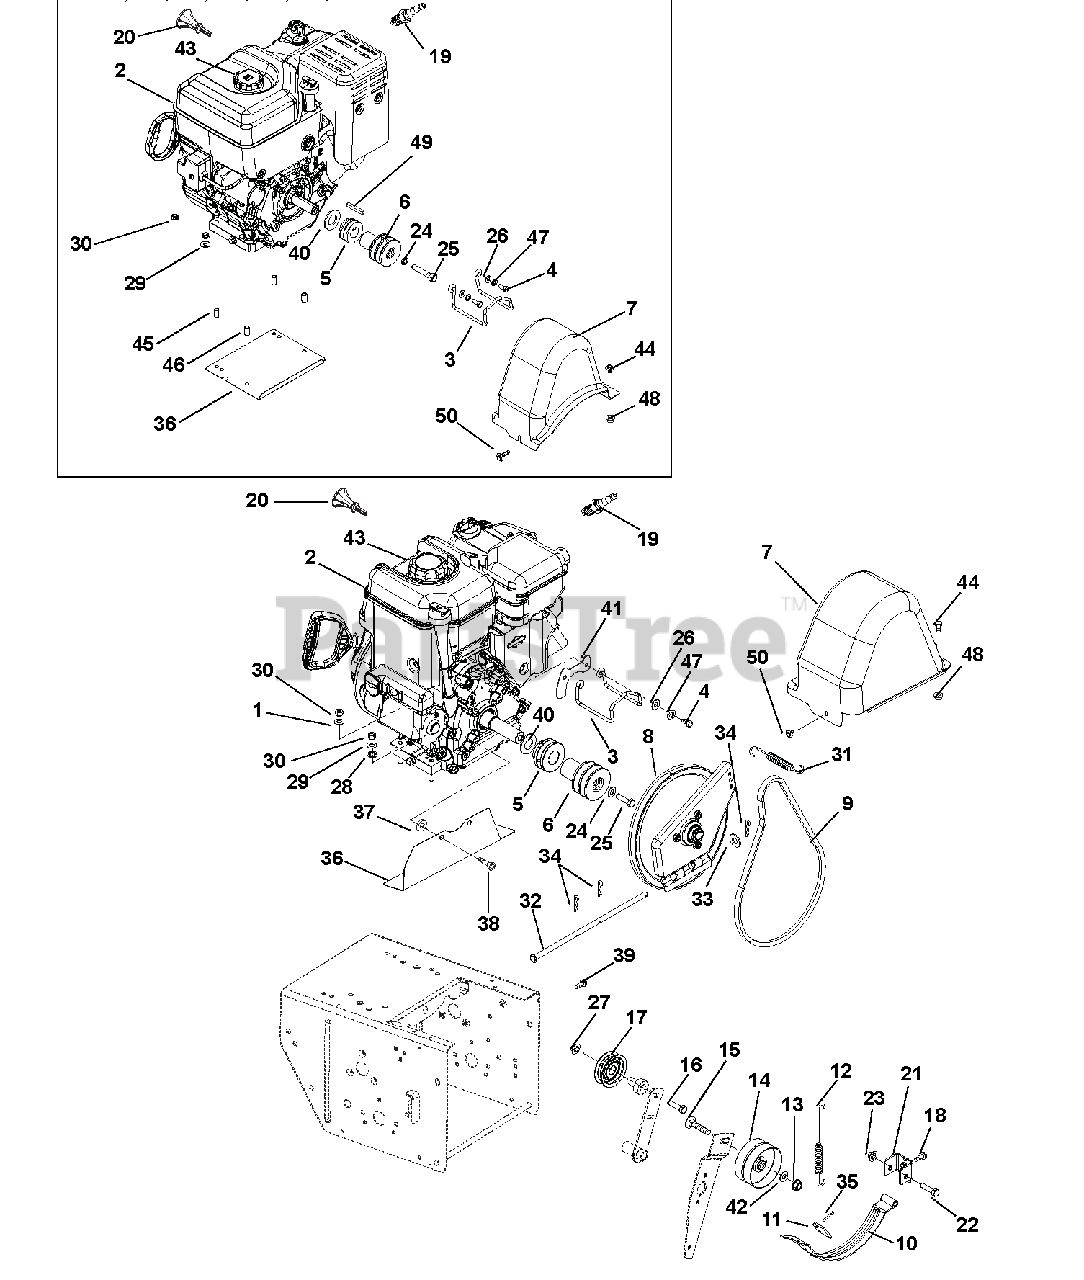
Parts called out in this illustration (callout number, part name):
1	WSHR-LK .312X.097 HVY YWZC
2	ENGINE, BRIGGS PF 1650, 12V
2	ENGINE, BRIGGS PF 2100, 120V
2	ENGINE, BRIGGS PF 2100, 240V
2	ENGINE, BRIGGS PF 2100, 12V
3	FINGER, BELT
4	BLT-HEX .31-24X.75 YWZC GR5
5	SHEAVE, DRIVE
5	SHEAVE, DRIVE 420 BRIGGS
6	SHEAVE, ATTACHMENT 2-GRV
7	COVER, BELT
7	COVER, BELT-LARGE PRO
8	PLATE, SWING ASSEMBLY-DEEP
9	V-BELT, 3L-WRAPPED
10	ARM, BRAKE-ATTACHMENT
11	PAD, BRAKE
12	SG-TENS .056X.60X4.40
13	@NUT-LK-CTR-JAM .375-16 YWZC
14	IDLER, FLAT-2.75 OD X .375 ID
15	@BLT-RHDSSQNK .38-16X1.75 G5YZ
16	@BLT-HEX .31-18X1.25 GR5 YWZC
17	KIT, FLAT IDLER
18	SCR-TAP .25-20X.50 HWH TR YWZ
19	PLUG, SPARK
19	PLUG, SPARK 20HP B&S VANGUARD
20	KEY, PUSH/PULL BRIGGS
20	KEY, IGNITION ROTARY B&S
21	PIVOT, BRAKE
22	@BLT-HEX .31-18X2.00 GR5 YWZC
23	@NUT-LK-TOP-FLG .31-18 YWZC
24	@WSHR-LK .38X.094 REG YWZC
24	@WSHR-LK .44X.109 REG YWZC
25	BLT-HEX .38-24X2.25 YWZC GR5
25	BLT-HEX .44-20X2.50 GR5 YWZC
26	@WSHR-FL-STL.344X.688X.065YWZC
27	@NUT-LK-TOP-FLG .31-18 YWZC
28	WSHR-LOCK INT .31 YWZC
29	@WSHR-FL-STL.344X.688X.065YWZC
29	@WSHR-FL-STL.38X.875X.083 YWZC
30	@NUT-LK-CTR .31-18 YWZC
30	@NUT-HEX .31-18 YWZC
30	@NUT-LK-CTR-FLG .31-18 YZ GR F
31	SG-TENS .048X.50X2.8
32	PIN, PIVOT
33	@WSHR-FL-STL.406X.812X.065 YWZ
34	PIN-HAIR, ENDRIES #25 YWZC
35	RVT-POP .187 YZ
36	BAFFLE, ENGINE
36	BAFFLE,ENGINE-PRO SERIES
37	WSHR-FL-STL .536X1.07X.109 YZ
38	SCR-MCH.31-24X.75FLCTRSK EP80
39	@SCR-TAP .25-20X1.50 HWH TR YZ
40	WSHR-FL-STL- 1.062X2.0X.134 YZ
40	WSHR,SPCR - 1.08X1.50X.131
41	GUARD, BELT COVER - BRIGGS
42	@WSHR-FL-STL.38X.875X.083 YWZC
43	CAP, FUEL - BRIGGS & STRATTON
44	SCR-TAP .25-20X.50 LGHWH TR YZ
45	BSHG-SLV .325X.400X.795
46	BSHG-SLV .328X.50X.75
47	WSHR-LK .312X.097 HVY YWZC
48	NUT-PUSH .25X.50 O.D.
49	KEY-SQ .25X.625X.25 SAE 8630
50	SCR-TAP .25-20X.5 CAPTIVE
